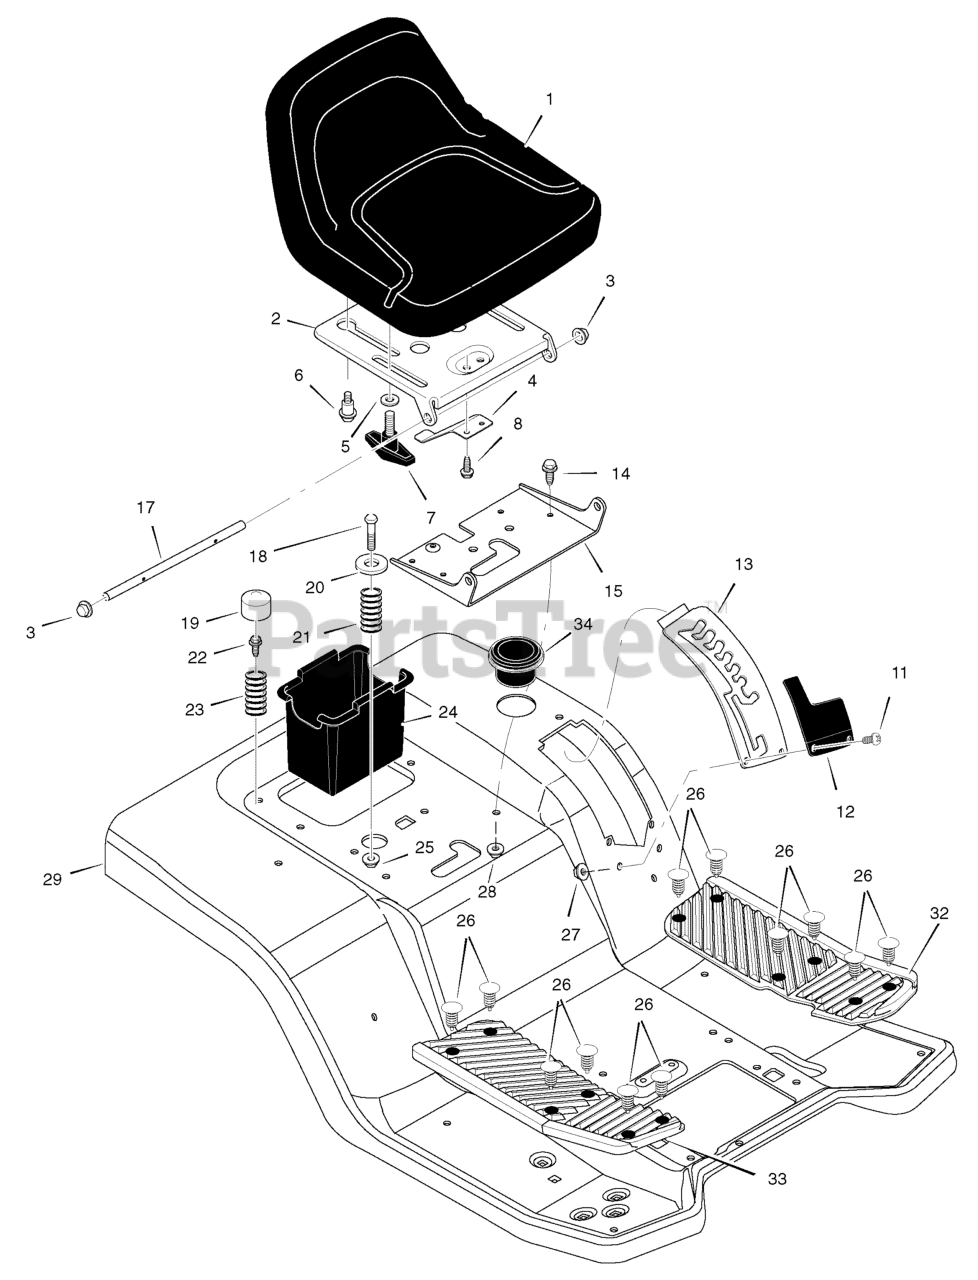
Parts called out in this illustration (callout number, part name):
2	Support, Seat
3	Cap, Push
4	Spring, Leaf
5	Washer
6	Bolt, Shoulder
7	Bolt, Wing
8	Screw
11	Bolt, Shoulder
12	Cover, Detent Lockout
13	Plate, Lift Detent
14	Bolt, Hex
15	Bracket, Pivot
17	Rod, Pivot
18	Bolt, Shoulder
19	Cap
20	Washer, Cup
21	Spring, Compression
22	Screw
23	Spring, Compression
24	Container, Battery
25	Nut, Centerlock
26	Fastener, Panel
27	Locknut
28	Nut, Nylock
29	Deck, Seat
32	Mat, Left
33	Mat, Right
34	Holder, Cup
